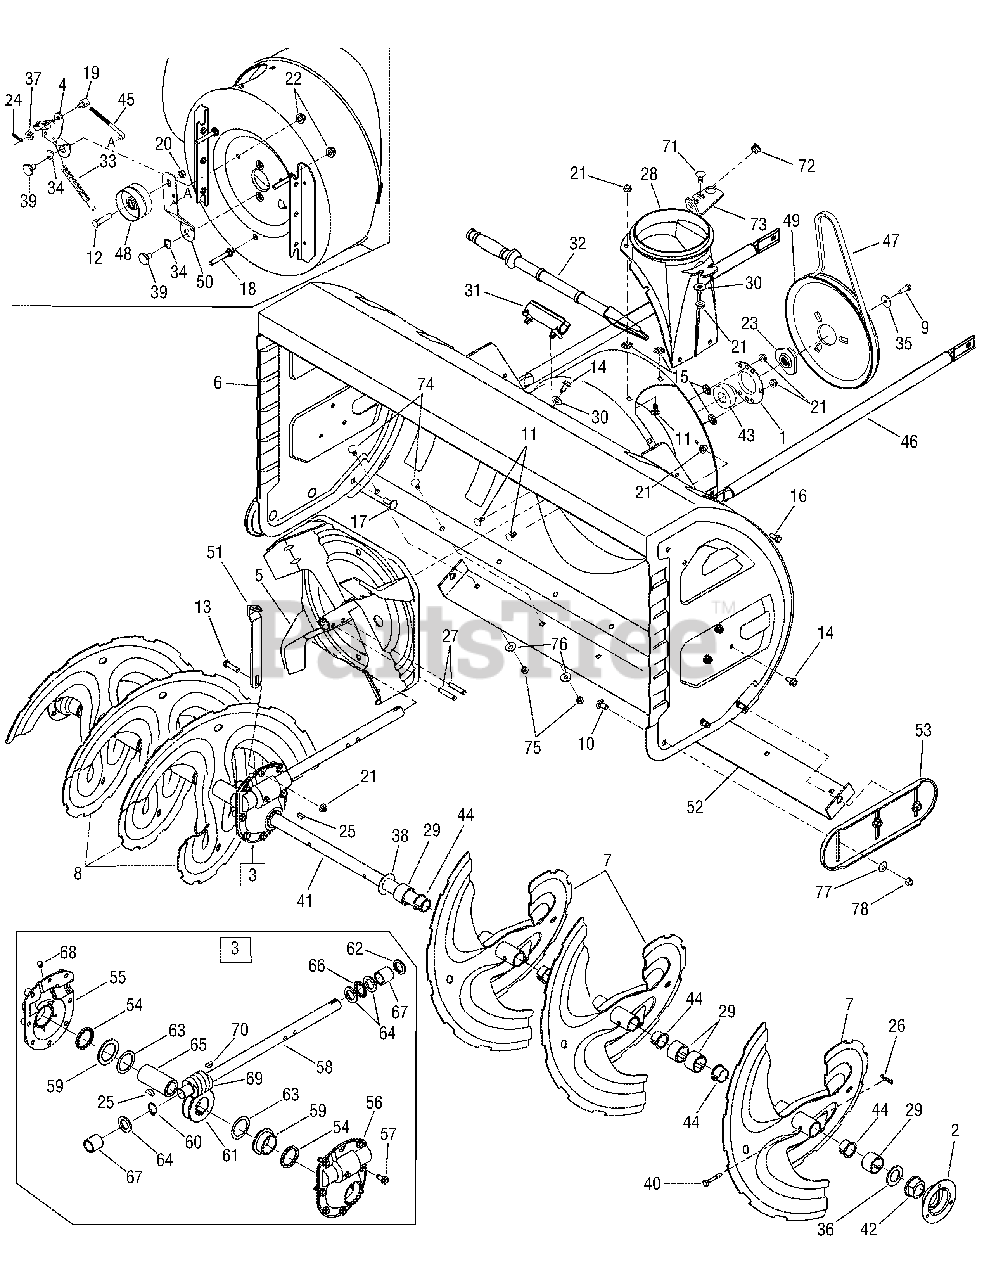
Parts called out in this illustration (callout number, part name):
1	Housing, Bearing
3	Gear Box Assembly
4	Bracket Ass’y, Auger Brake
9	Screw, Hex Cap Lock, 5/16-24 x .875 Gr8
10	Screw, Carriage, 3/8-16 x .75 Stainless
11	Screw, Carr, 5/16-18 x .75
12	Screw, Hex Cap, 3/8-24 x 1.5
13	Screw, Hex Cap, 5/16-18 x 1.0 Gr5
14	Screw, 5/16-18 x .750
16	Screw, 5/16-18 x .75 GR5
17	Screw, Carr,3/8-16 x 1.0 Stainless
18	Screw w/Stud, 5/16-18 x .4300
19	Ferrule
20	Nut, Hex Lock, 3/8-24
21	Nut, Hex Flange Lock, 5/16-18
22	Nut, Hex Flange Lock, 3/8-16
23	Adapter, Pulley w/Pins
24	Pin, Internal Cotter
25	Key, Woodruff, 1/4 x 3/4
26	Pin, Bowtie Cotter
27	Pin, Spirol, 5/16 x 1.75
28	Adapter, Chute, 6"
29	Spacer, 1.0 x 1.5 x 1.0Lg
30	Washer, Flat, .349 x .879 .063
31	Clip, Mounting
32	Tool, Cleanout
33	Spring, Extension
34	Washer, Wave, .625 x .885 x .015
35	Washer, Flat, .34 x 1.5 x .15 HT
36	Spacer, 1.004 x 1.375 x .25
37	Washer, .344 x .75 x .12
38	Washer, 1.01 x 1.86 x .06
39	Screw, Shoulder, .625 x .17
40	Pin, Shear, .25 x 1.75
41	Shaft, Spiral, — 45"
42	Bearing, Flange w/Flats
43	Bearing, Self Aligning
44	Bushing, Flange,
45	Rod, Auger Idler
48	Pulley, Flat Idler, 2.75 OD
49	Pulley, Auger Drive, 10.0
50	Bracket, Auger Idler
54	Oil Seal
55	Hsg, Ass’y, Auger, RH (Incl. Ref. # 54 & 59)
56	Hsg, Ass’y, Auger, LH (Incl. Ref. # 54 & 59)
56	Fitting, Lube
57	Scr, LD, 5/16-18 x .750
58	Shf, Drive, Auger
59	Flange Bearing
60	Ext, Ret, Ring
61	Gear, Worm, LH
62	Seal, Oil
63	Wash, Flat, 1.52ID x 2.0 OD
64	Wash, Flat, .88 ID x .38 OD
65	Shf, Gear, Worm
66	Bearing, Thrust
67	Sleeve
69	Gear, Worn
70	Key, Hi Pro, 3/16 x 3/4
71	Screw, Carriage, 5/16-18 x 1.0
72	Bushing, Plastic, .38 ID
74	Screw, Carriage, 5/16-18 x .75 Stainless
75	Nut, Hex, 5/16-18 Stainless
76	Washer, Bell., .34 x .872 x .06 Stainless
77	Washer, Bell., .375 x .87 x .063 Stainless
78	Nut, Hex Lock, 3/8-16 Stainless
